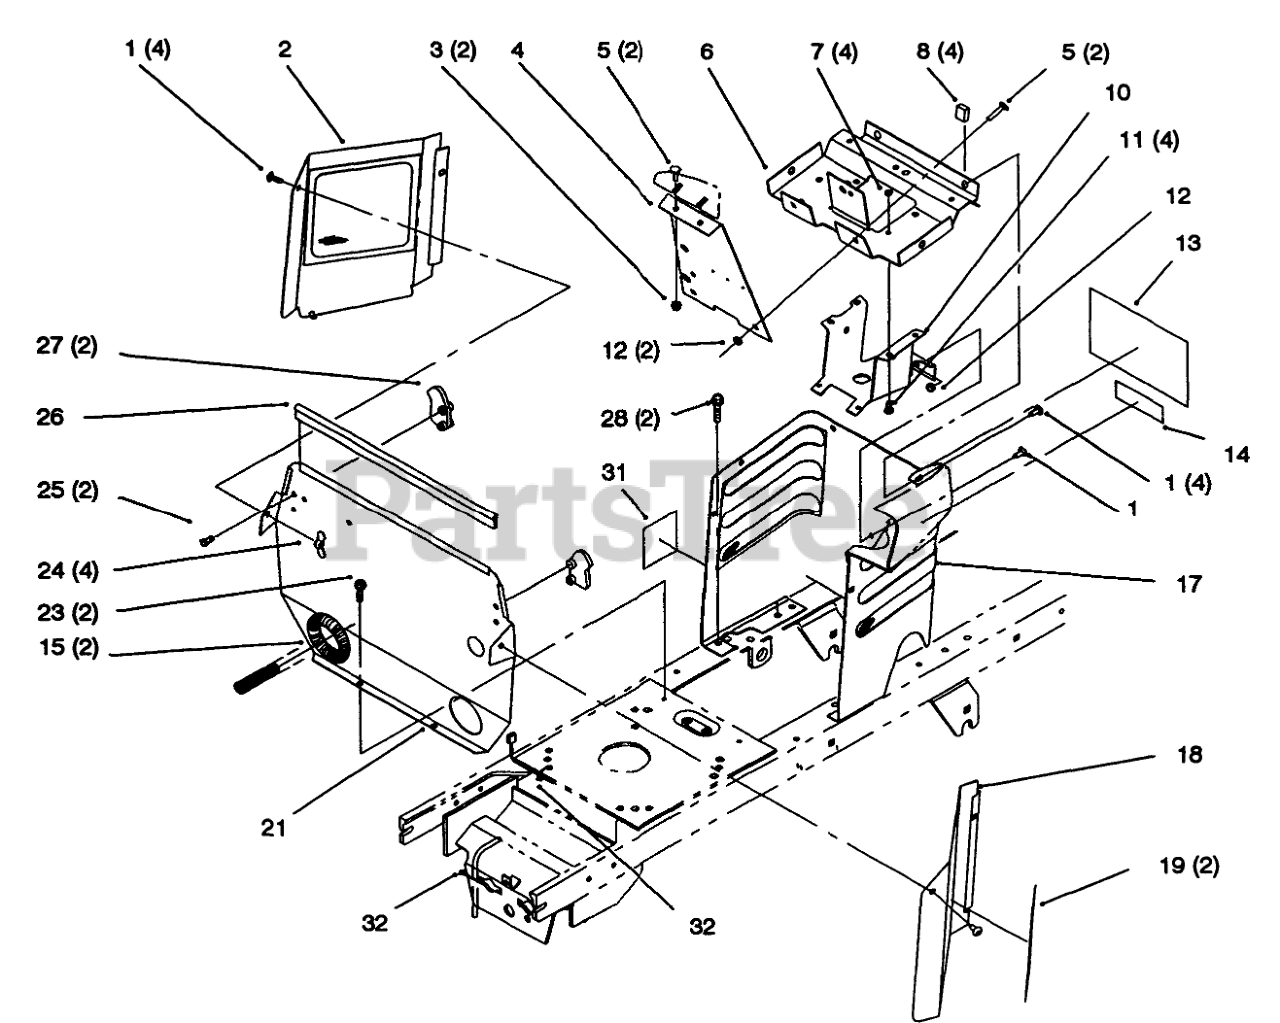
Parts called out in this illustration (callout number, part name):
1	SCREW-HH
2	RH SIDE COVER ASM
3	NUT-KEPS
4	PANEL-SUPPORT DASH (BLACK)
5	SCREW-CARR
6	SUPPORT-DASH
7	NUT-HEX
8	NUT RETAINER - J TYPE
10	BRACKET-COLUMN, LOWER
11	SCREW-HH
12	NUT-LOCK, NI
13	Decal-Slope/Park Brake (Only On: 72062)
13	Decal-Slope/Park Brake (Only On: 72063, 72103)
13	Decal-Slope/Park Brake (Only On: 72042)
13	Decal-Slope/Park Brake (Only On: 72043, 72083)
14	DECAL-INSTRUCTION
15	COVER-SHAFT, DRIVE
17	Hoodstand W/Decals (Only On: 72042)
17	Hoodstand W/Decals (Only On: 72043, 72083)
17	Hoodstand W/Decals (Only On: 72062)
17	Hoodstand W/Decals (Only On: 72063, 72103)
18	LH COVER ASM
19	Decal-264-6 (Only On: 72042, 72062)
19	Decal-264-H (Only On: 72043, 72063)
19	Decal-266-H (Only On: 72083, 72103)
21	FIREWALL (BLACK)
23	SCREW-HWH
24	NUT-WING
25	SCREW-PLASTITE
26	TRIM-SEAL, FIREWALL
27	LATCH-HOOD
28	SCREW-HWHTF
31	Decal-Noise (Only On: 72103, 72063, 72062)
32	TIE-CABLE
